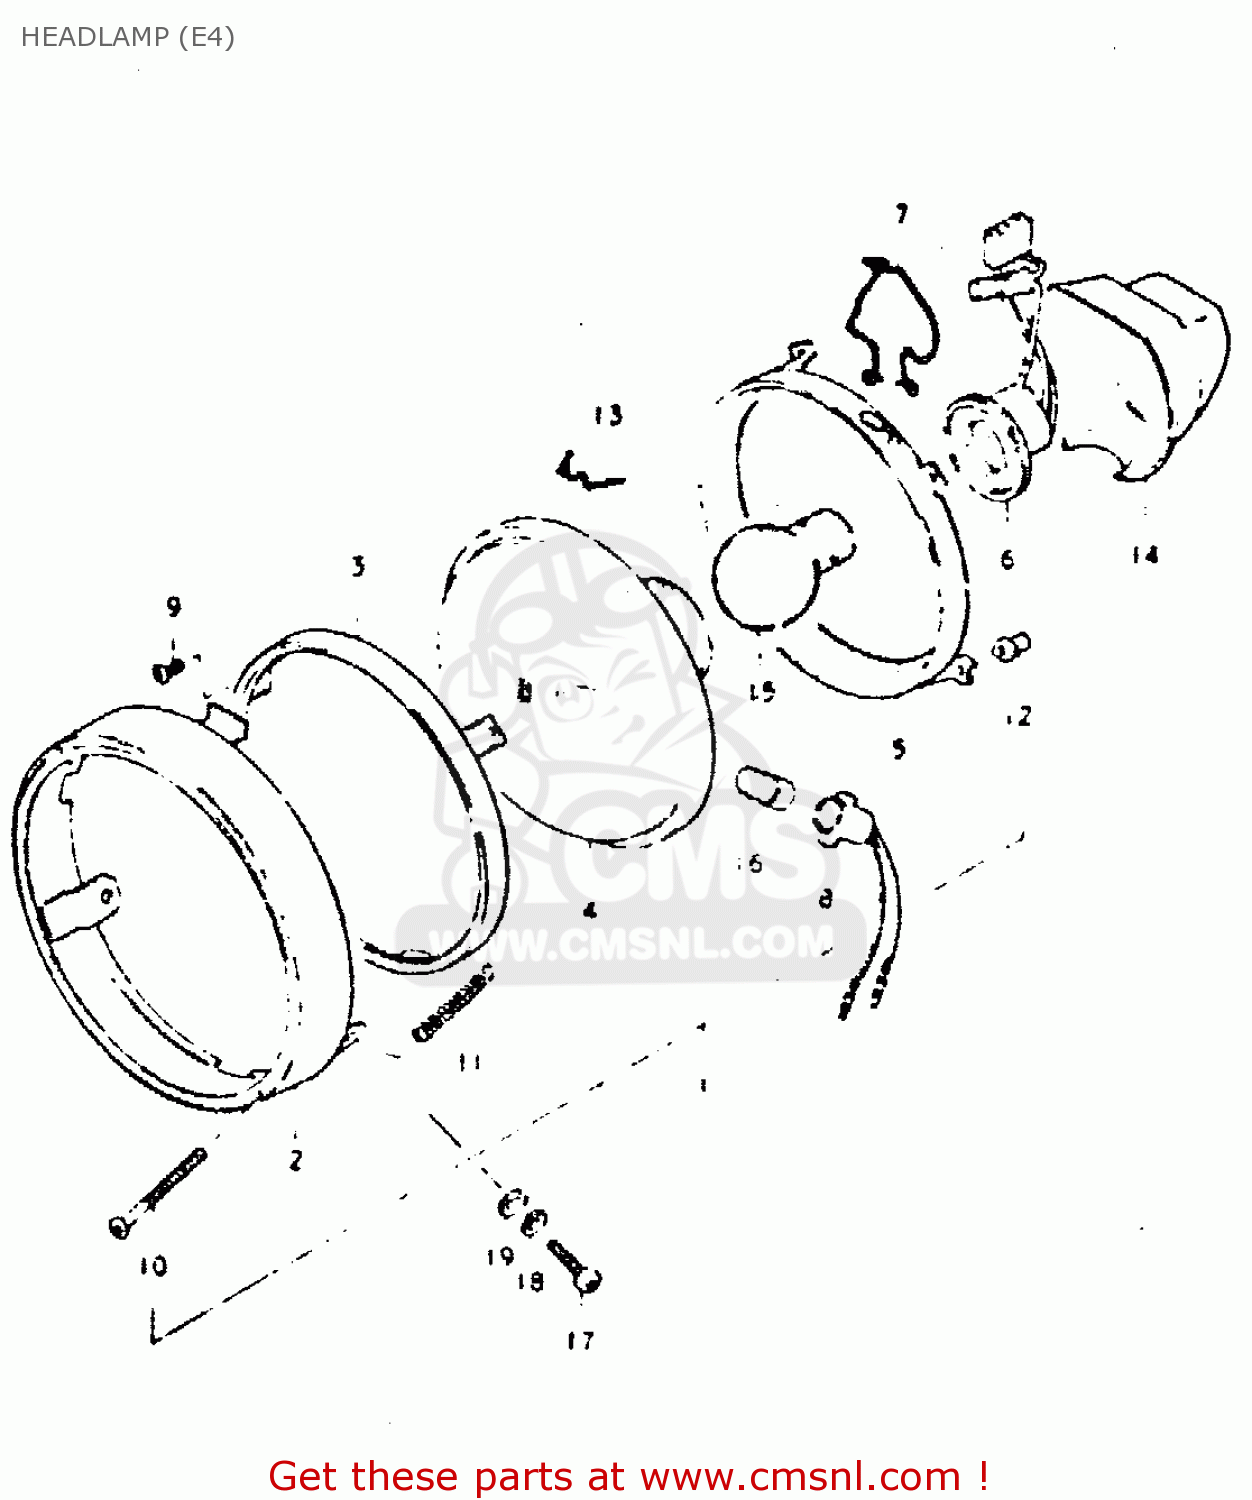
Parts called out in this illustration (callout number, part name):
1	HEADLAMP ASSY
2	RIM
3	RETAINER,HEADLAMP
4	UNIT
5	RING, MOUNTING
6	SOCKET
7	CLAMP,HEADLAMP
8	SOCKET
9	SCREW
10	SCREW,HEADLAMP ADJUST
11	SPRING,ADJUSTING
12	NUT,HEADLAMP ADJUSTER
13	SPRING,HEADLAMP UNIT
14	COVER, SOCKET
15	BULB (6V,36/36W)
16	BULB (6V,4W)
17	SCREW
18	LOCK WASHER
19	WASHER
